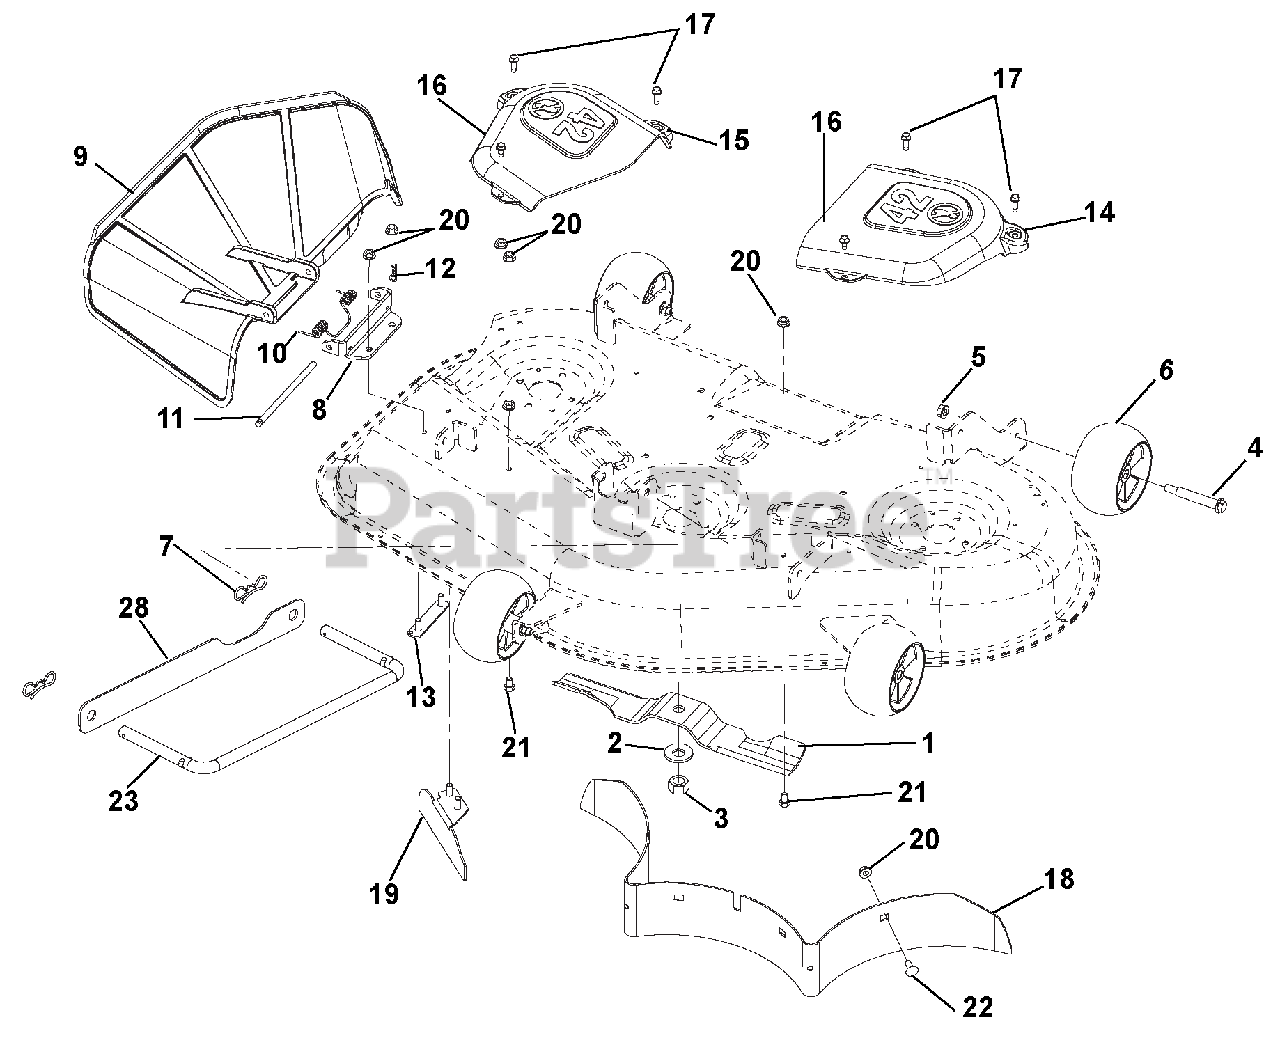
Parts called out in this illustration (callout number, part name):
1	BLADE, MOWER 14.83 (.188 THK)
2	WSHR-BLVL .669X1.535X.138
3	NUT-HEX .62-18 YWZC
4	BLT-SHLDR .38-16X2.50 HWH G5
5	@NUT-LK-TOP-FLG .38-16 YWZC
6	ANTI-SCALP WHEEL - 5X OS
7	PIN,BOW TIE LOCKING .091X1.875
8	BRKT-DISCHARGE CHUTE MOUNT 42"
9	CHUTE, DISCHARGE - MOLDED
10	SPRING-TORSION
11	PIN, 5/16 X 5.80"
12	PIN-HAIR INT .08X.18X1.18 YWZC
13	WMT-DISCHARGE CHUTE MT. STRAP
14	BELT COVER - LH 42"
15	BELT COVER - RH 42"
16	SCR-TAP .25-20X.50 HWH TR YWZ
17	SCR-TAP .25-20X.75 HWH TR YWZ
18	BAFFLE, REAR (42)
19	WLDMT-BAFFLE, DISCHARGE 42"
20	@NUT-LK-TOP-FLG .31-18 YWZC
21	@BLT-HEX .31-18X.50 GR5 YWZC
22	@BLT-RHDSSQNK .31-18X.75 G5YZ
23	WIREFORM, DRAG LINK
24	@BLT-HEX .38-16X3.50 GR5 YWZC
25	@WSHR-FL-STL.406X.812X.065 YWZ
26	@NUT-LK-CTR-JAM .375-16 YWZC
27	@NUT-LK-NYL-FLG .38-16 YWZC
28	STRAP, DRAG LINK
